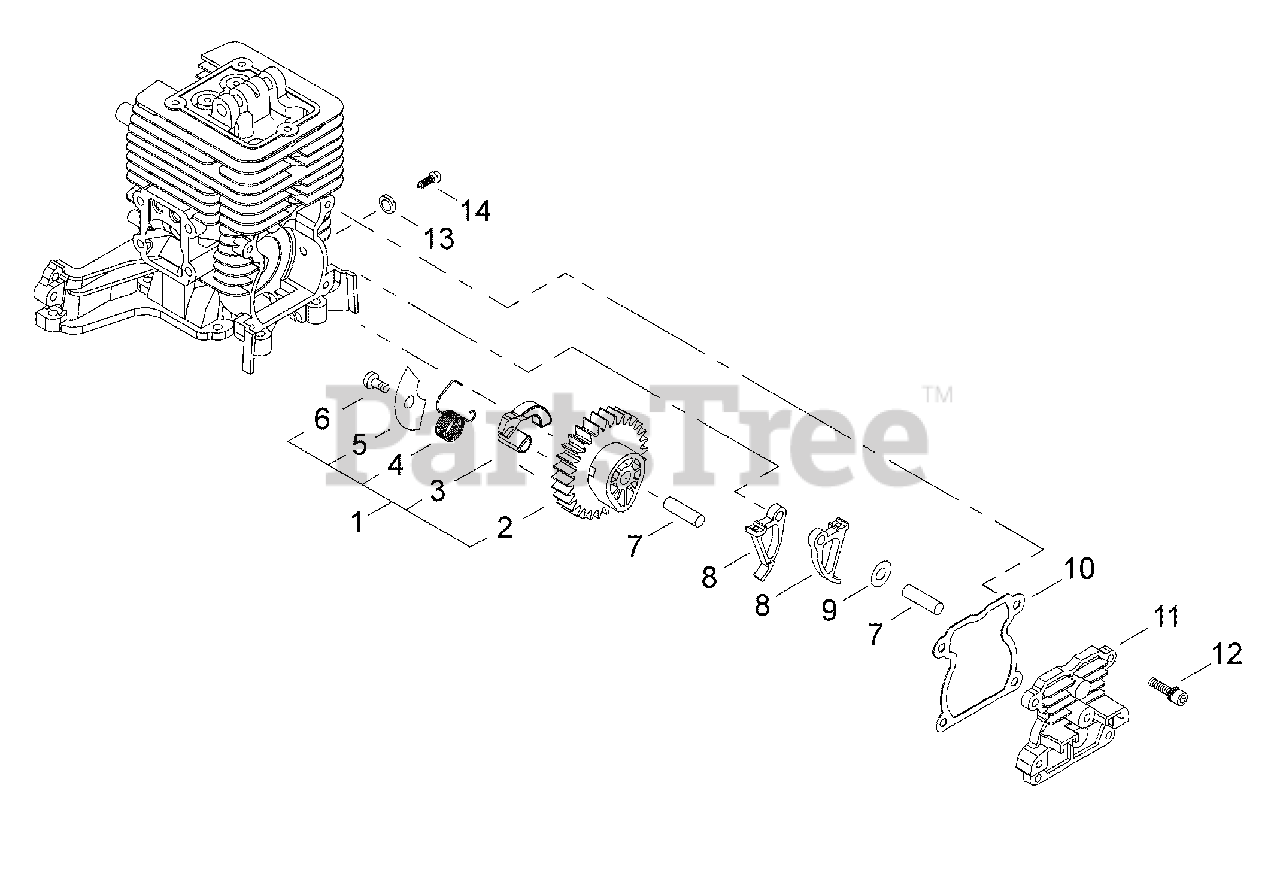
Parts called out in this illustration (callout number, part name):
1	CAM GEAR ASSY
2	GEAR, CAM
3	WEIGHT
4	SPRING
5	PLATE, COVER
6	SCREW, TAPPING 4×6
7	PIN, LOCATING Ø5×29.8 MM
8	FOLLOWER, CAM
9	WASHER 5 MM
10	GASKET, CAM GEAR
11	COVER, CAM GEAR
12	BOLT M4×14
13	WASHER Ø10ר5.5×2
14	SCREW M5
